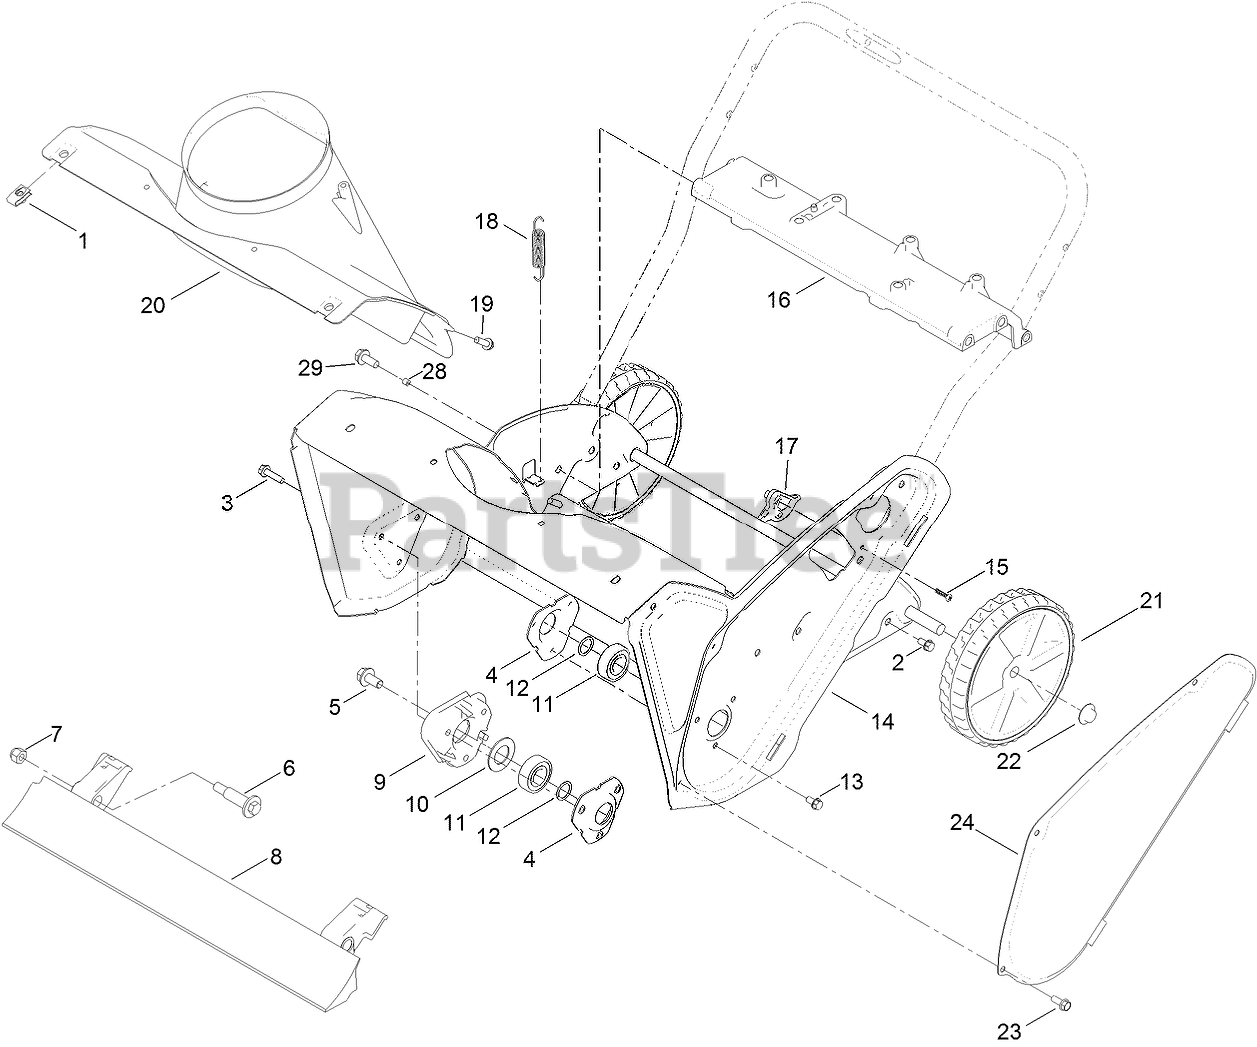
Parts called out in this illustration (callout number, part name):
2	SCREW-HWHTF
3	SCREW-HWHTF
4	FLANGE-BEARING
5	SCREW-HWH
6	BOLT-WHEEL
7	NUT-LOCK, NI
8	BLADE-SCRAPER
9	SPACER-BEARING, RH
10	WASHER-RUBBER
11	BEARING-BALL
12	WASHER-THRUST
13	SCREW-HWH
14	HOUSING-AUGER
15	SCREW-PPH
16	BRACE-FRAME
17	GUIDE-CABLE, CLUTCH
18	SPRING-EXTENSION
19	SCREW-HWH
20	CHUTE-LOWER
21	WHEEL ASM
22	NUT-PUSH
23	SCREW-HWH
24	COVER-BELT
28	SPACER
29	SCREW-HWHTF
